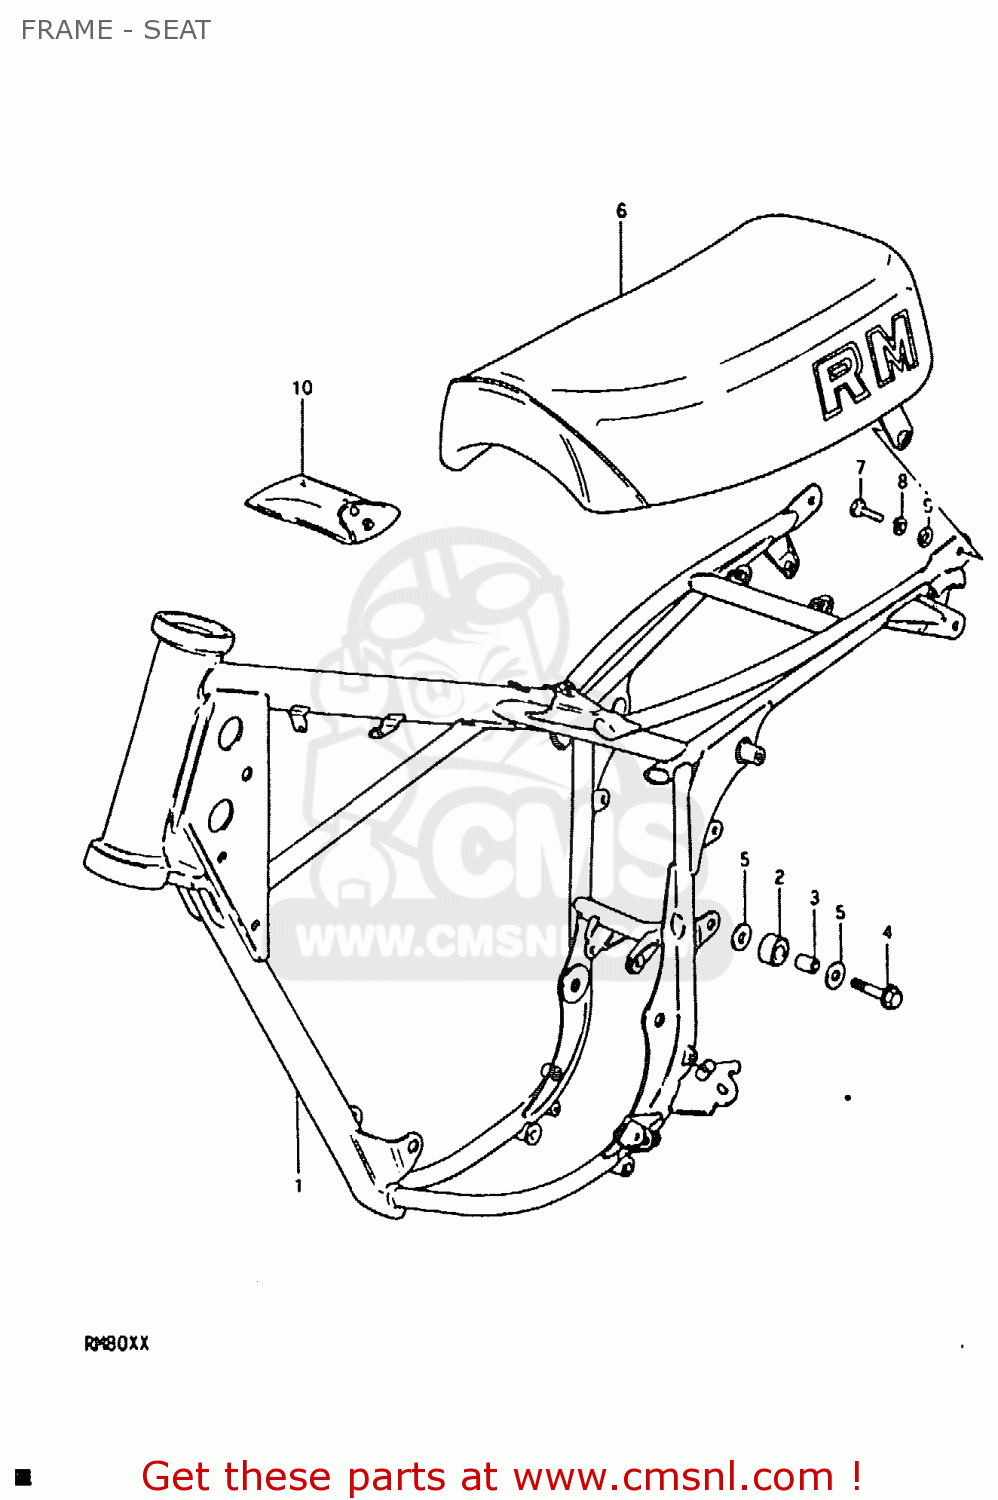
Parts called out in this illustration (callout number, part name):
1	FRAME
2	ROLLER,CHAIN CONTROL
3	SPACER,CHAIN CONTROL
4	BOLT(8X45)
5	WASHER
6	SEAT ASSEMBLY
7	BOLT
8	LOCK WASHER
9	WASHER
10	TOOL SET
